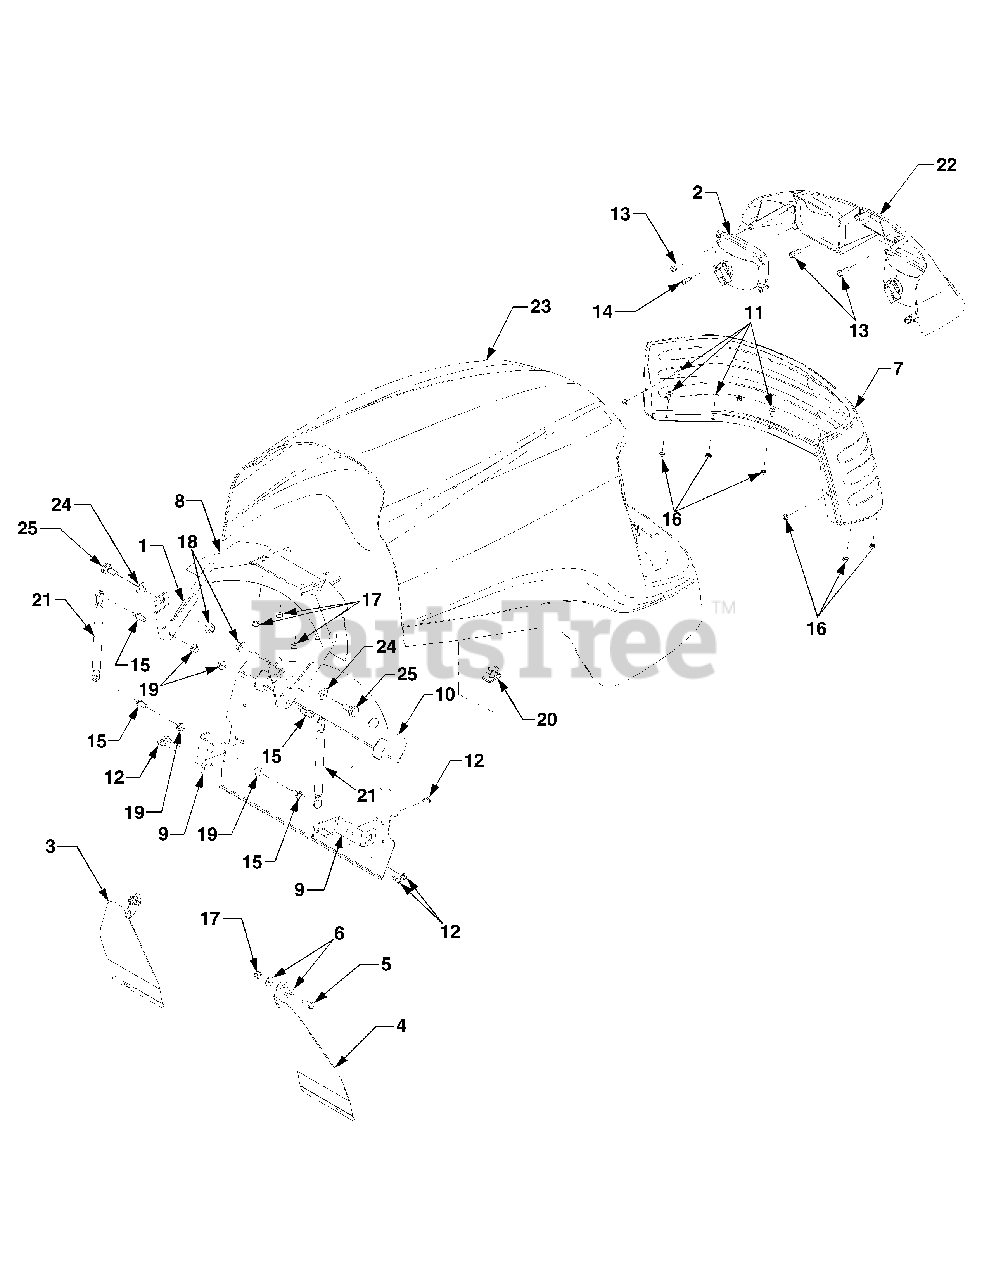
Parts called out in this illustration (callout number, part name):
1	Hinge Assembly, Hood
2	Headlight Assembly
2	Bulb Assembly, Headlight
3	Shield, Running Board LH
4	Shield, Running Board RH
5	Screw, Hex Cap, 1/4-20 x .75 GR5
6	Washer, Flat, .26 x .72 x .060
10	Shield, Lower Heat
11	Screw, Truss Hd, 10-24 x .5
12	Screw, Hex Wash Hd Tapp 1/4-20 x .5
13	Screw, Hex Wash. Hd. 1/4-20 x .75
14	Screw, Truss Phil. Hd. 12-16 x .75
15	Stud, Cylinder, 5/16-18 Thrd
16	Nut, Hex Sems, 10-24
17	Nut, Hex Nylon Insert Lock, 1/4-20
18	Nut, Hex Flange Lock, 3/8-16
19	Nut, Hex Flange Lock, 5/16-18
20	Clip, Retaining
21	Cylinder, Gas Spring
22	Bezel, Headlight
23	Hood, Service Kit
23	Hood
23	Graphic, Hood RH
23	Graphic, Hood LH
23	Graphic, Model 5252 LH
23	Graphic, Model 5252 RH
24	Washer, Flat, .531 x .93 x .090
25	Screw, Shoulder, .5 x .27 Lg 3/8-16
